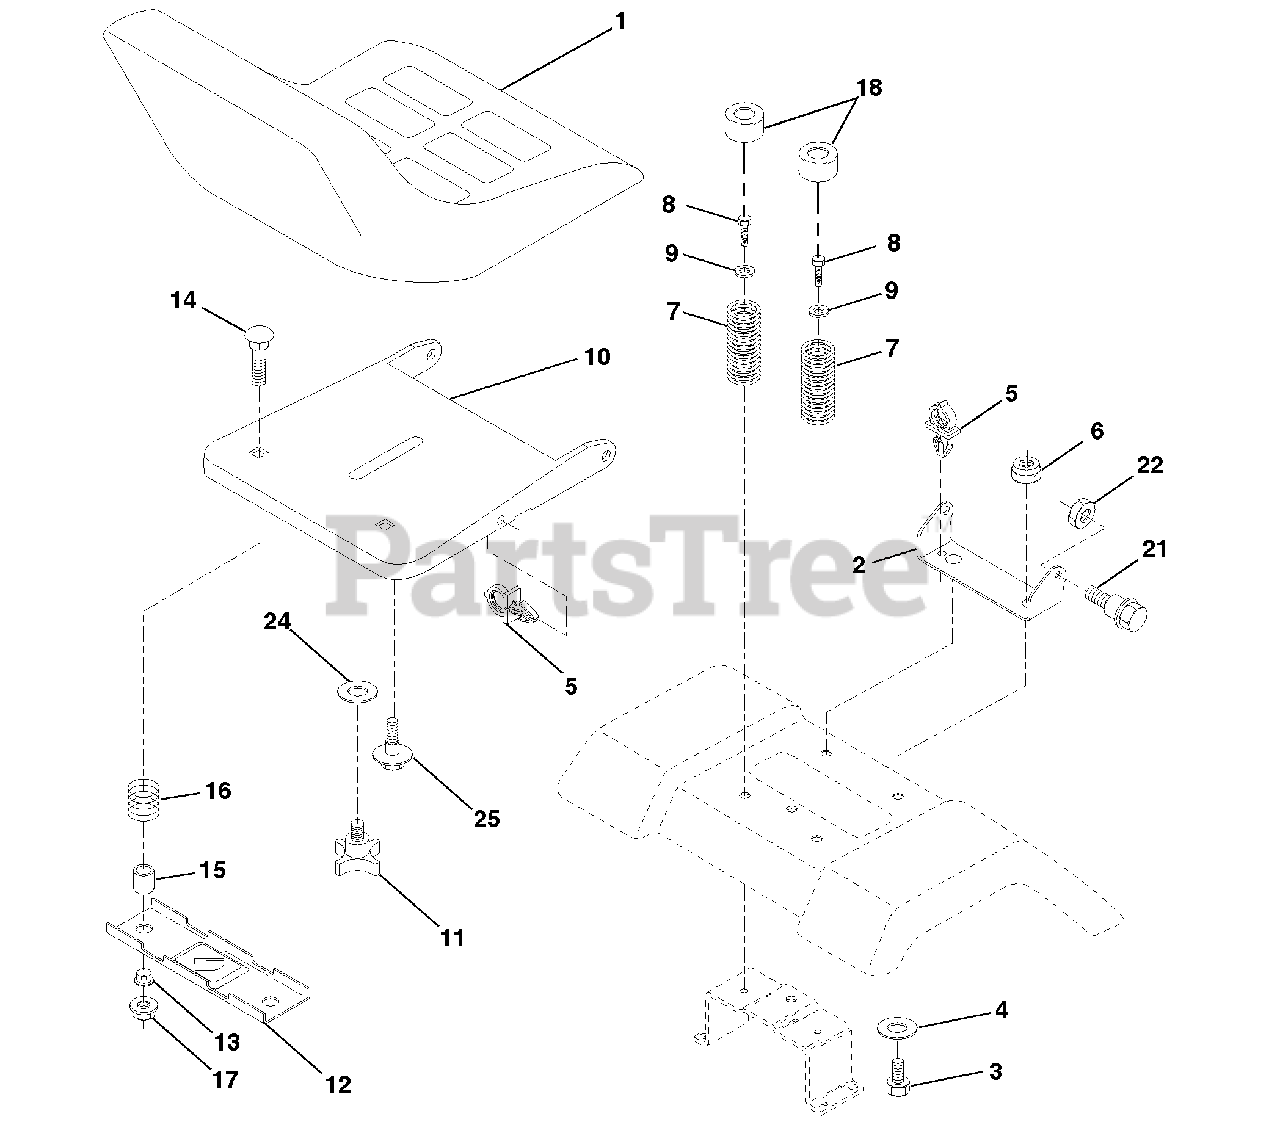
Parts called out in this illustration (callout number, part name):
1	Seat
2	Bracket Pivot Seat 8 720
3	Bolt Fin Hex 3/8-16unc x 1
4	Washer 13/32 x 1 x 10 Ga
5	Clip Push-In
6	Nut Hex w/Ins. 3/8-16 Unc
7	Spring Seat Cprsn 2 250 Blk Zi
8	Screw Thdrol 3/8-16 x 1 Ty-tt
9	Washer 13/32 x 1 x 14 Ga.
10	Pan, Seat
11	Knob, Seat
12	Bracket Mounting Switch
13	Bushing Snap Blk Nyl 50 Id
14	Bolt Rdhd Sqnk 1/4-20 x 1-1/2
15	Spacer Split 28 x 96 Yel Zinc
16	Spring Cprsn 1 27 Blk Pnt
17	Nut Lock 1/4 Lge Flg Gr 5 Zinc
18	Cap Spring, Seat Blk 1.75 x 1.0
21	Bolt Shoulder 5/16-18 Unc
22	Nut Hex Lock W/Ins 5/16-18
24	Washer 17/32 x 1-3/16 x 12 Ga.
25	Bolt Shoulder 5/16-18 x 62
